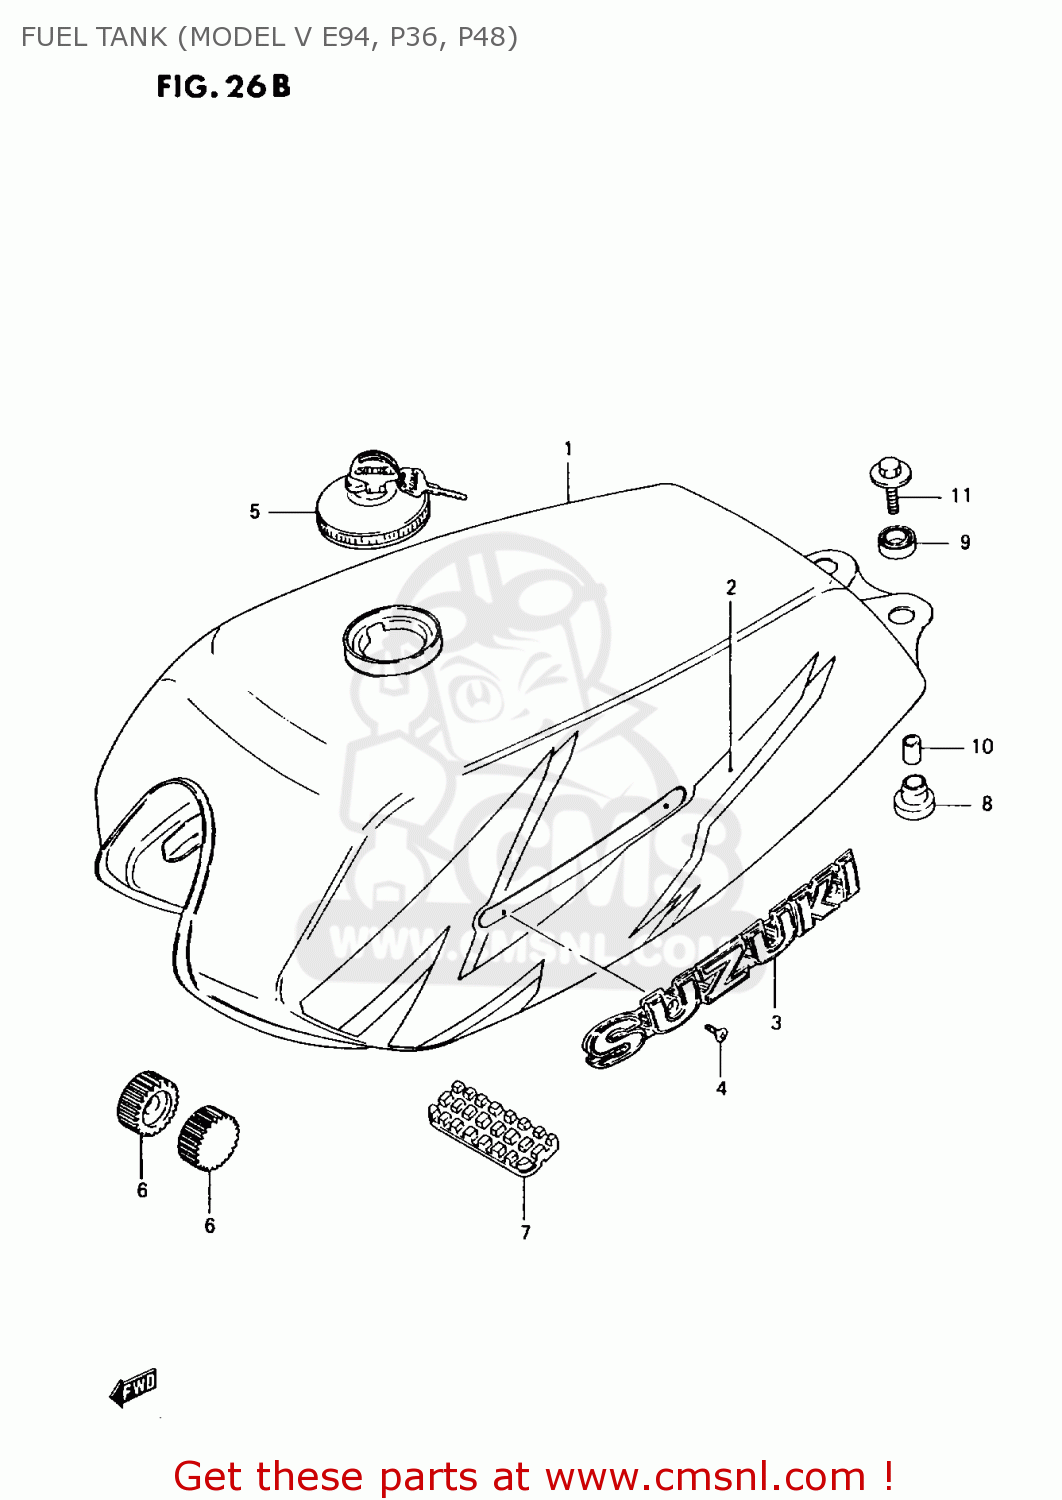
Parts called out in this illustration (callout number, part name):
1	TANK ASSY, FUEL (RED)
2	TAPE SET, FUEL TANK
3	EMBLEM,FUEL TANK
4	SCREW
5	CAP SET,FUEL TANK
6	CUSHION
7	CUSHION
8	CUSHION
9	CUSHION
10	SPACER(6.5X9X18)
11	BOLT(6X30)
